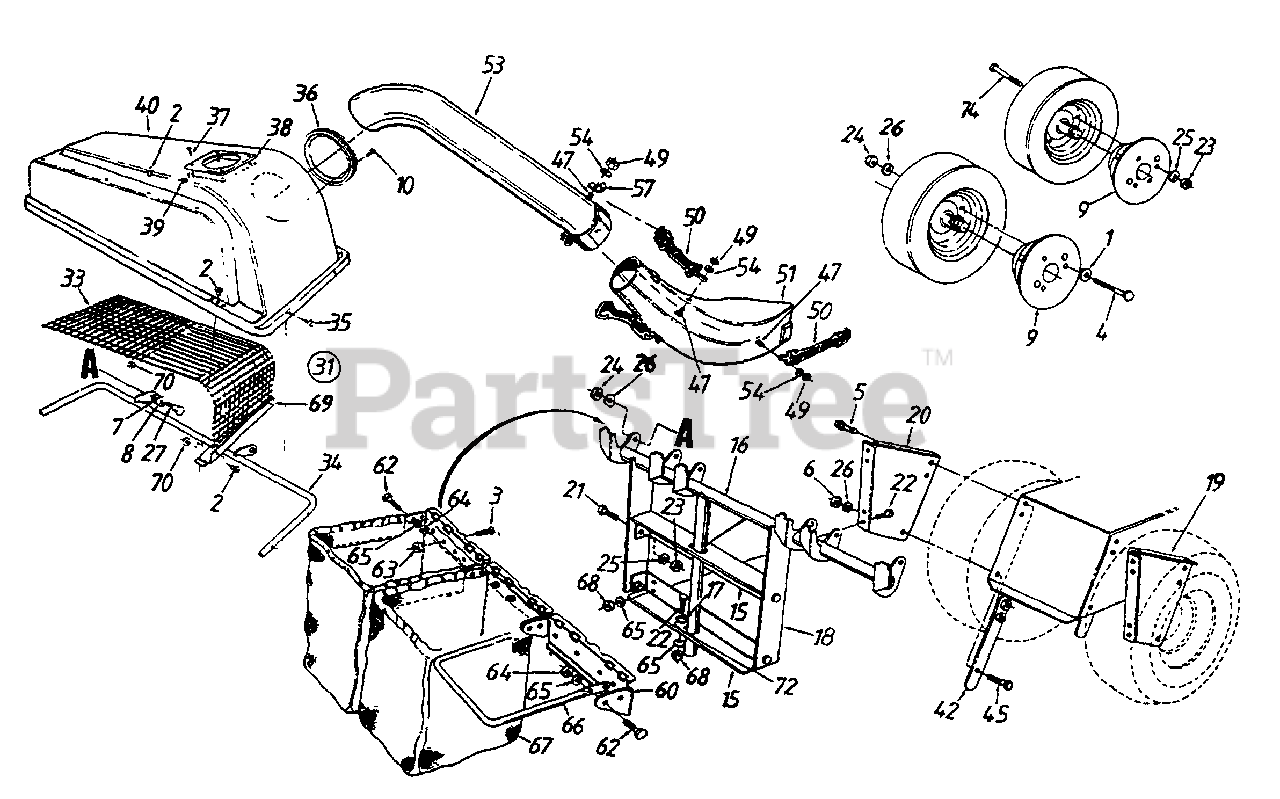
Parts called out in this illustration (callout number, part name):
1	Fl-Wash. .385" I.D.
2	Pop Rivet
3	Truss Mach. Scr. #10-24 x .5"
4	Hex Bolt 3/8-16 x 4.5" ig.
5	Hex Wash. Hd. Tap Scr. 5/16-18 x .62"
6	Hex Nut 3/8-24 Thd.
7	Bell-Wash. .515" I.D.
8	Fl-Wash. .510" I.D.
22	SCREW 1/4-20 x .620 GR5
23	Hex Nut 5/16-18 Thd.
24	Hex Nut 3/8-16 Thd.
25	L-Wash. 5/16" I.D.
26	L-Wash. 3/8" I.D."
27	Shld. Bolt 3/8-16 x .500" Dia.
31	Catcher Cover Ass'y. Comp.
33	Screen
36	Tube Seal
37	Truss Mach. B-Tap Scr. #10 x .5" Lg.
38	Plastic Plate
39	Speed Nut
40	Grass Catcher Cover
47	Hex Bolt 1/4-20 x .50" Lg.
49	Hex Ins. L-Nut 1/4-20 Thd.
50	Retainer Strap Ass'y.
51	Discharge Chute
53	Catcher Elbow Tube
54	L-Wash. .270" I.D. x.57" O.D.
57	Retainer Hook Brkt.
62	Hex Bolt 1/4-28 x .88" Lg.
63	Hex Sems Nut 010-24 Thd.
64	Hex Nut 1/4-28 Thd.
65	L-Wash. 1/4" I.D.
66	Catcher Bag Frame
67	Grass Catcher Bag
68	HEX NUT 1/4-20
74	Hex Bolt 5/16-18 x 4" Lg.
